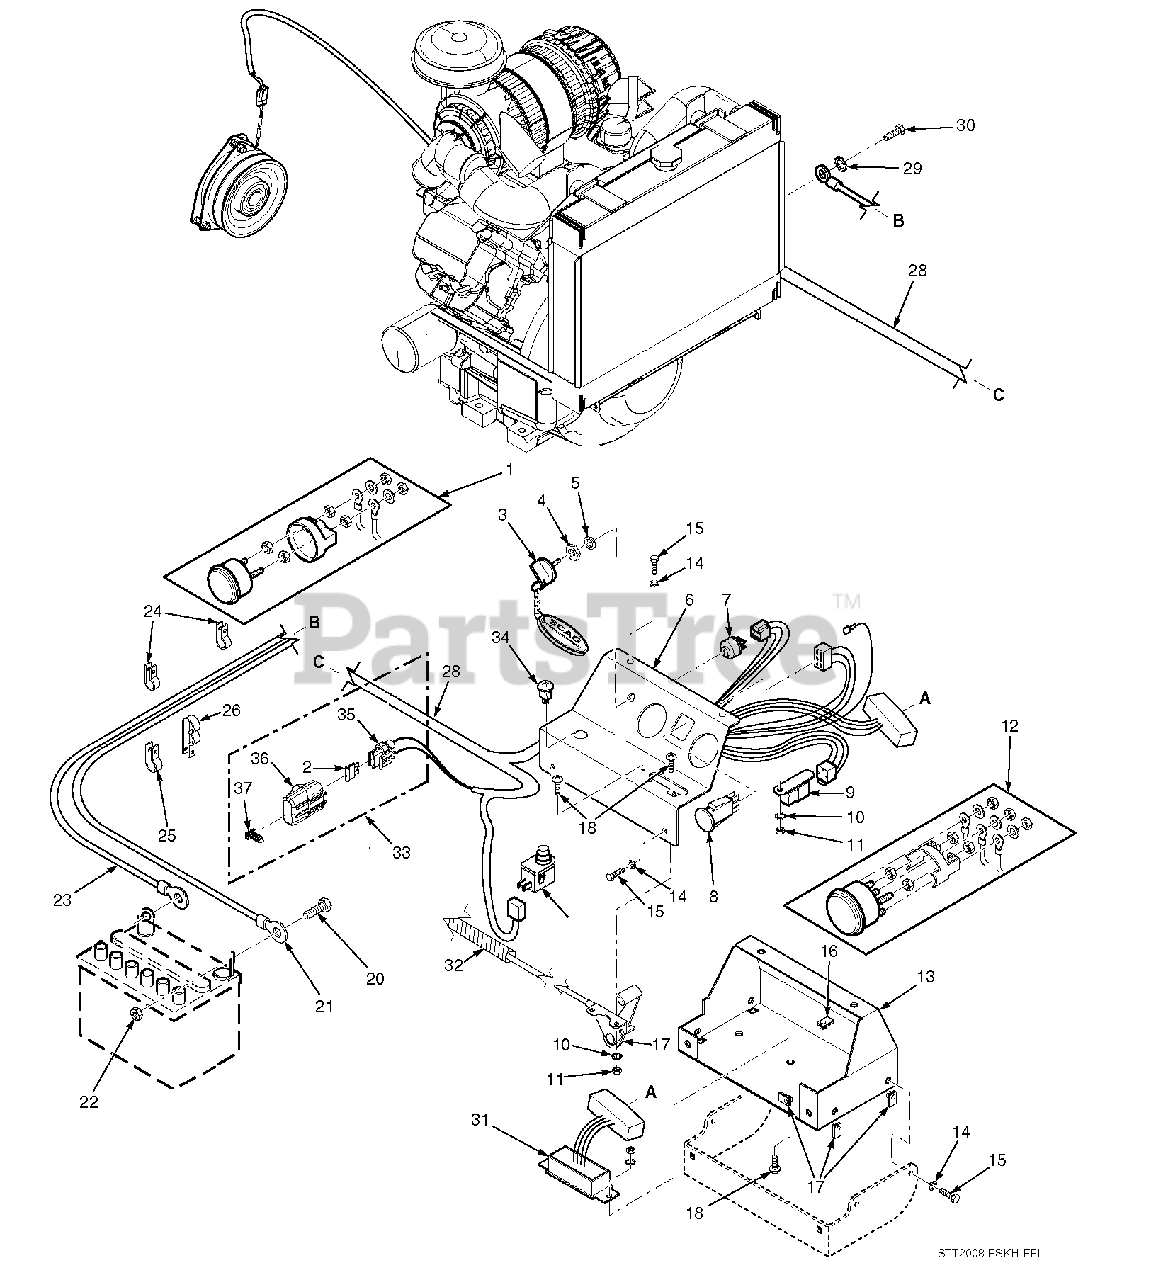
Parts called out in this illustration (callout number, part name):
1	Volt Meter
2	Fuse, 20 AMP
3	Key, Assembly w/Fob
4	Nut, Hex 5/8-32
5	Lockwasher, 5/8" Internal
6	Instrument Panel, Top w/Decals
7	Key Switch
8	Switch, PTO - 10 Amp
9	Relay
10	Lockwasher, #10 External Tooth
11	Nut, Hex #10-32
12	Water Temp. Gauge
13	Base, Instrument Panel
14	Lockwasher, 1/4"
15	Bolt, Hex Hd. 1/4-20 x 3/4"
16	U-Nut, 1/4-20
17	Throttle Controls
18	Screw, Phillips Washer Head #10-32 x 1/2"
19	Switch, Interlock-Seat
20	Bolt, Hex Hd. 1/4-20 x 1/2"
21	Cable, Battery - Red
22	Nut, Hex 1/4-20
23	Cable, Battery - Black
24	Clamp, Cable 1/2" I.D.
25	Clamp, Cable 3/4" I.D.
26	Clamp, Cable
27	Sending Unit, Water Temp.
28	Wire Harness, STT Liquid-Cooled Electronic Fuel Injection
29	Lockwasher, 5/16" External Tooth
30	Bolt, Hex Hd. M8-1.25 x 20mm
31	Electronic Module
32	Heatshield, Flexible
33	Single Fuse Assembly, Sealed
34	Indicator Light, Check Engine
35	Fuse Holder
36	Cover, Sealed Single
37	Clip, Wire
